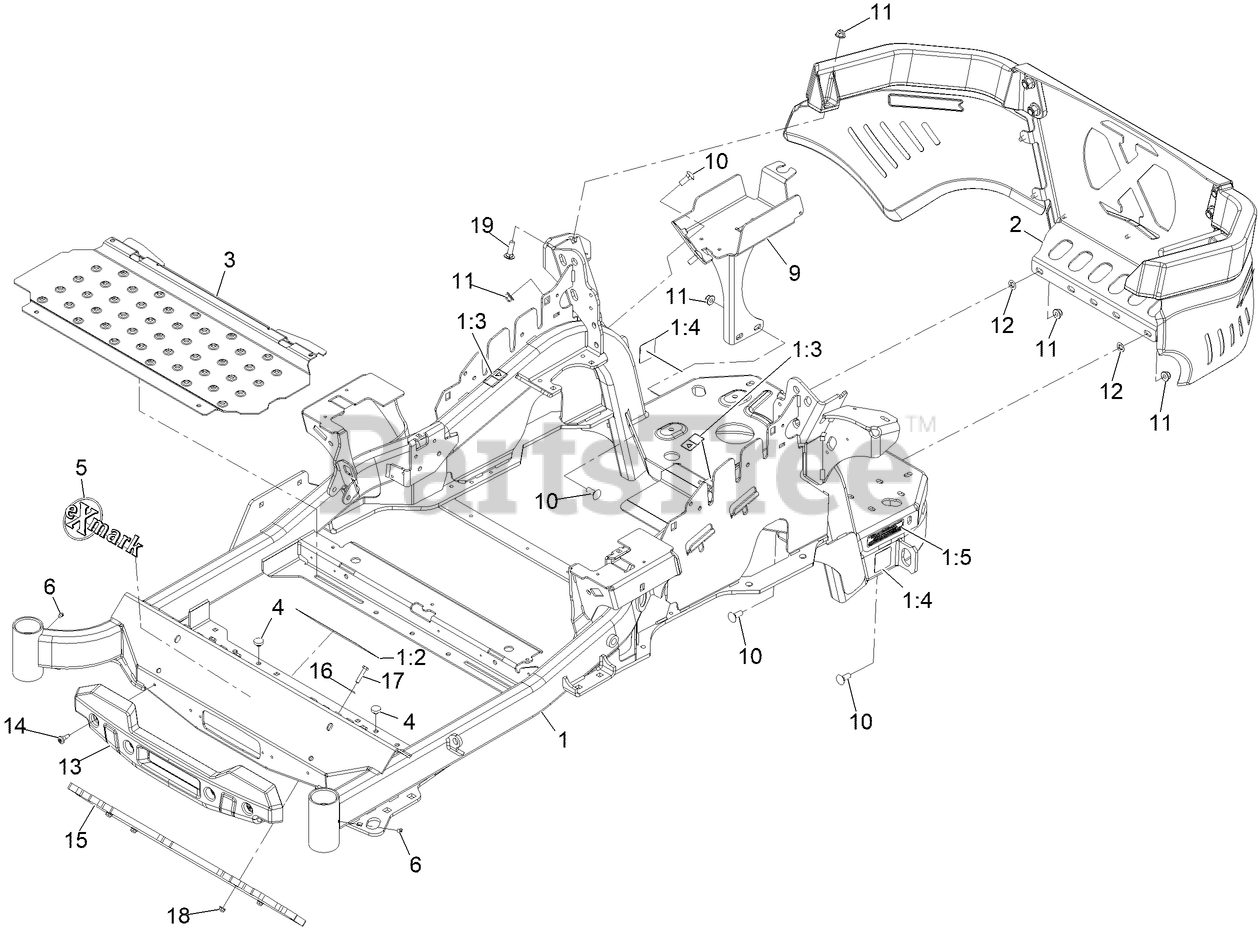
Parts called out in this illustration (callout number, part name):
1	Asm-Main Frame W/Decals
1:2	DECAL-DANGER
1:3	DECAL-WARNING
1:4	DECAL-HAZARD, PINCHED FINGER
1:5	DECAL-ARRESTOR, SPARK
2	Cage-Rear
5	EMBLEM-EXMARK
9	Weld-Battery Mount
10	BOLT-CARR
11	NUT-HF, NI
12	NUT-PUSH
13	BUMPER-FRONT
14	SCREW-SHOULDER
15	Weight-Toe Board
16	WASHER-FLAT
17	SCREW-HH
19	BOLT-CARR
